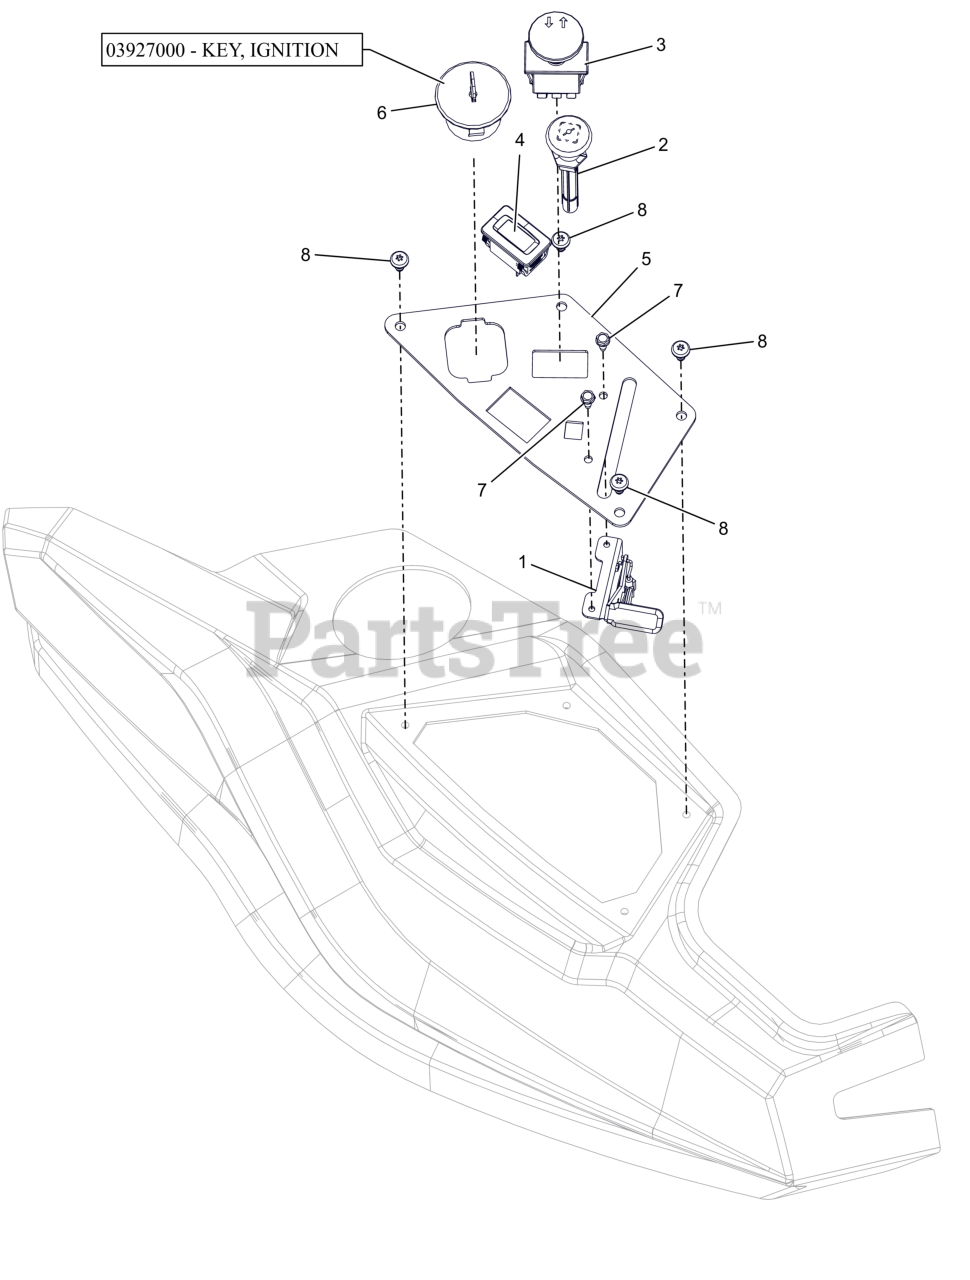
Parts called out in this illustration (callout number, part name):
1	CABLE, THROTTLE
2	CABLE, CHOKE (SNAP IN)
3	SWITCH, CLUTCH (YELLOW)
4	HOUR METER
5	PANEL, CONTROL (ORANGE)
6	KEYSWITCH-IGNITION 3 POS
6	KEY, 03290500 KEYSWITCH
7	SCR,TAP #10-24X.50 HWH TR ZCC
8	SCR-PAN .25-15X.50 6L H/LZB500
